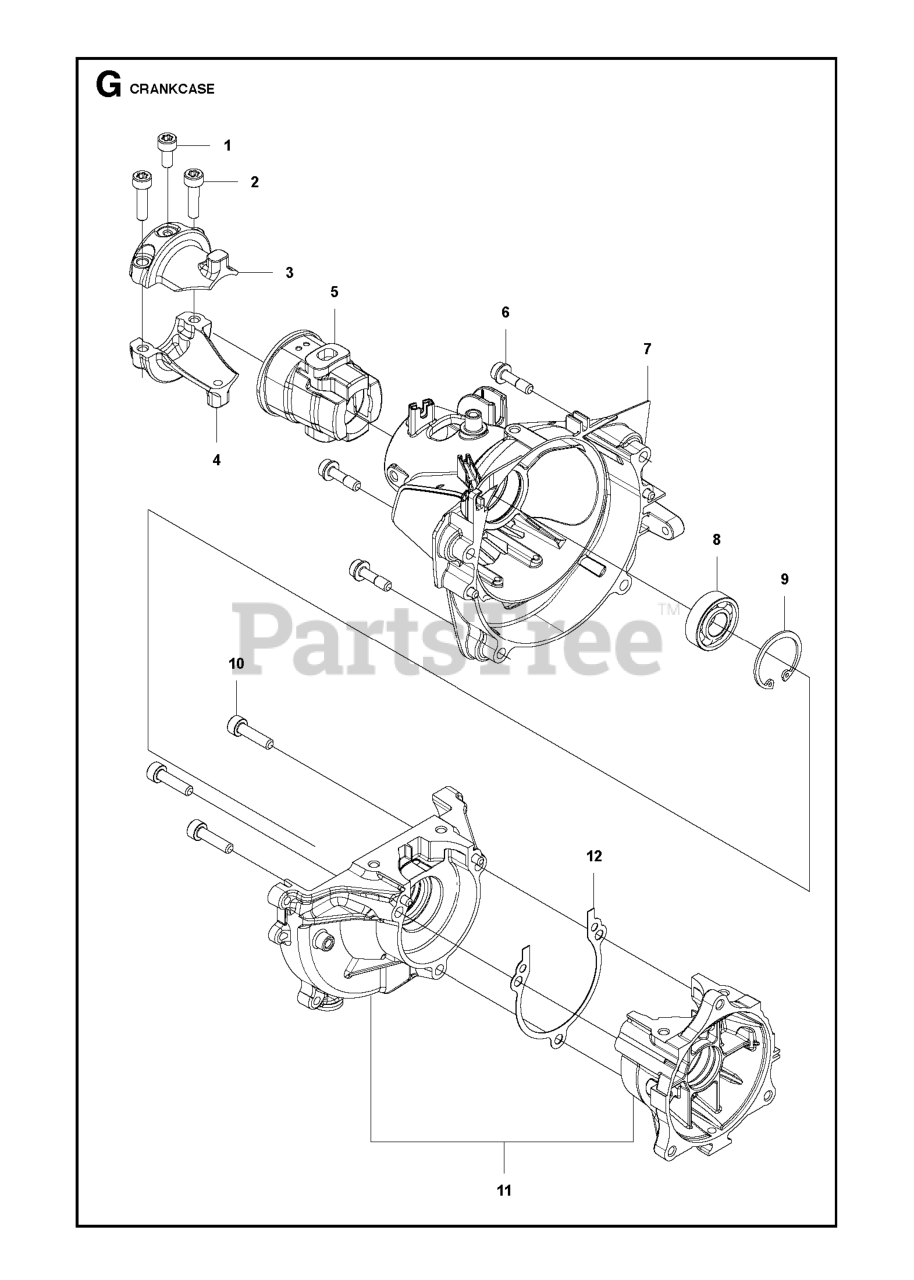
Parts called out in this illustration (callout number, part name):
1	SCREW ITXSCM M5X8
2	BOLT M5X20 T27
3	BRACKET UPPER M5X0.8
4	BRACKET LOWER
5	CUSHION UPPER
6	BOLT
7	HOUSING CLUTCH
10	BOLT
11	CRANKCASE COMP
12	GASKET CASE
